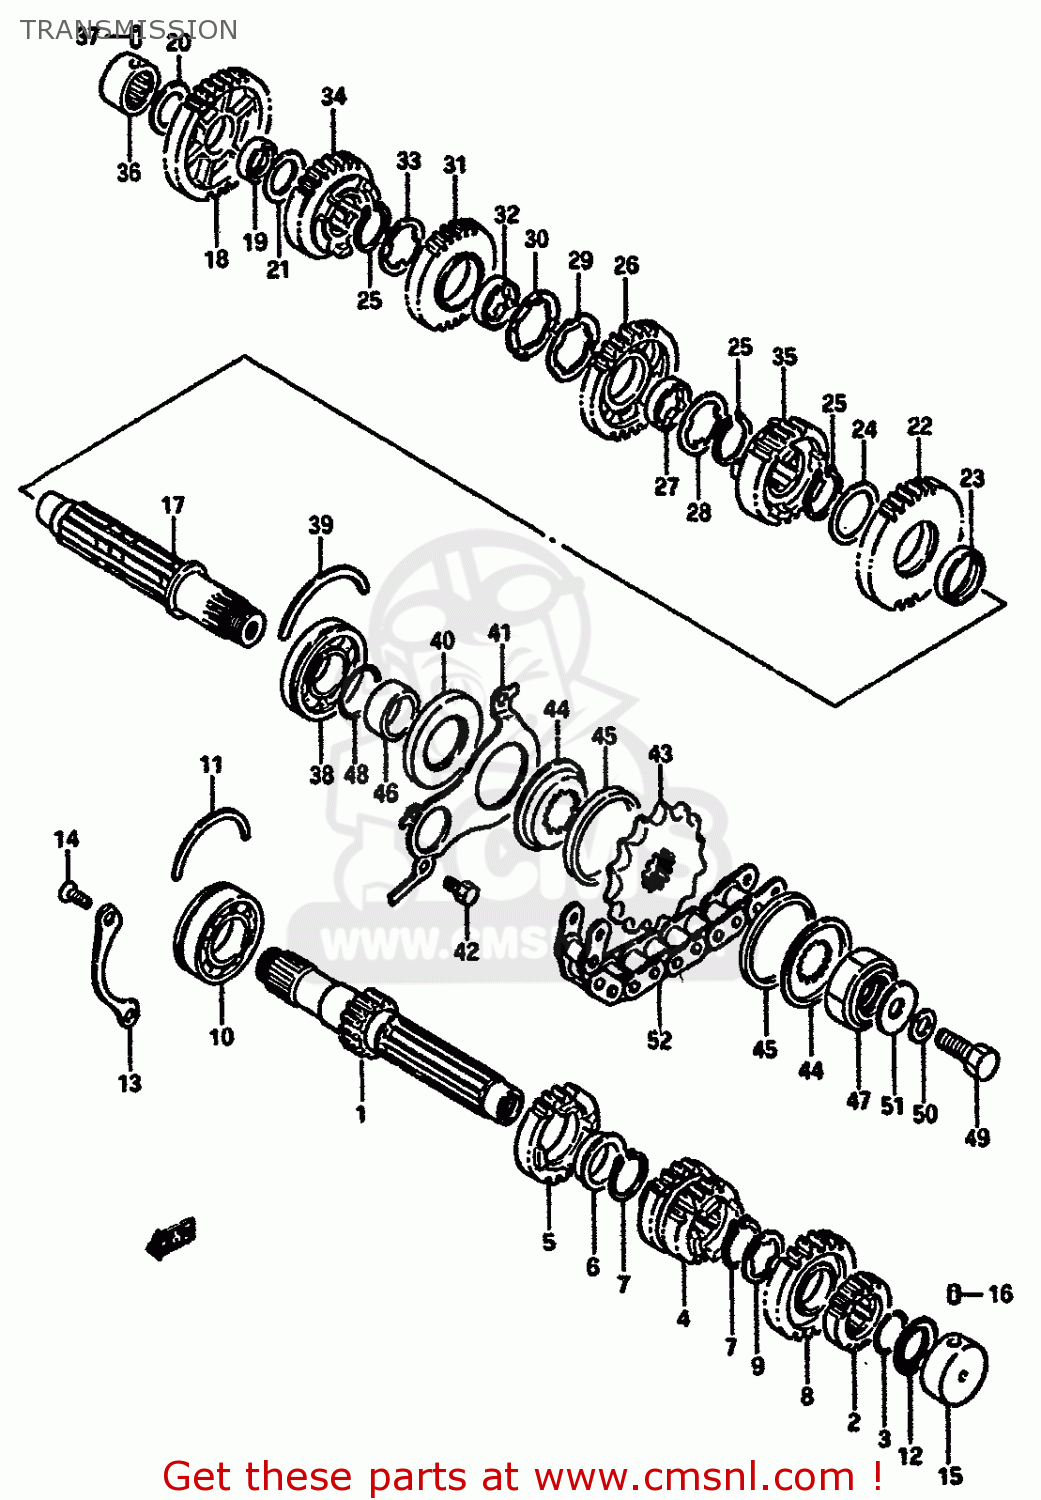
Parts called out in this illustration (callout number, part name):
1	SHAFT,COUNTER
2	GEAR,2ND DRIVE(NT:16)
3	RING,SNAP
4	GEAR,3RD & 4TH DRIVE(NT:17/20)
5	GEAR,5TH DRIVE(NT:22)
6	BUSHING
7	RING,SNAP
8	GEAR,SIXTH DRIVE
9	WASHER,LOCK
10	BEARING(25X62X17)
11	C-RING
12	SEAL,OIL(20X31.2X2.7)
13	RETAINER,CNTR SHAFT BEARING
14	SCREW
15	BEARING(20X34X17.5)
16	PIN
17	SHAFT,DRIVE
18	GEAR,1ST DRIVEN(NT:36)
19	BUSH(22X26X9)
20	WASHER
21	WASHER
22	GEAR,SECOND DRIVEN
23	BUSH(28X32X8)
24	WASHER, THRUST
25	CIRCLIP
26	GEAR,3RD DRIVEN(NT:28)
27	BUSH
28	WASHER,LOCK
29	WASHER,LOCK
30	WASHER
31	GEAR,FOURTH DRIVEN
32	BUSH
33	WASHER,LOCK
34	GEAR,5TH DRIVEN(NT:27)
35	GEAR,SIXTH DRIVEN
36	BEARING(20X34X20)
37	PIN
38	BALL BEARING 25X62X17
39	C-RING
40	SEAL,OIL(34X62X6)
41	RETAINER,DRIVESHAFT O
42	BOLT
43	SPROCKET,ENGINE
44	HOLDER,SPROCKET DAMPER
45	DAMPER,SPROCKET
46	SPACER (25X34X16.1)
47	NUT
48	O RING(D:1,ID:24.5)
49	BOLT
50	WASHER,LOCK
51	WASHER
52	CHAIN ASSEMBLY,DRIVE
